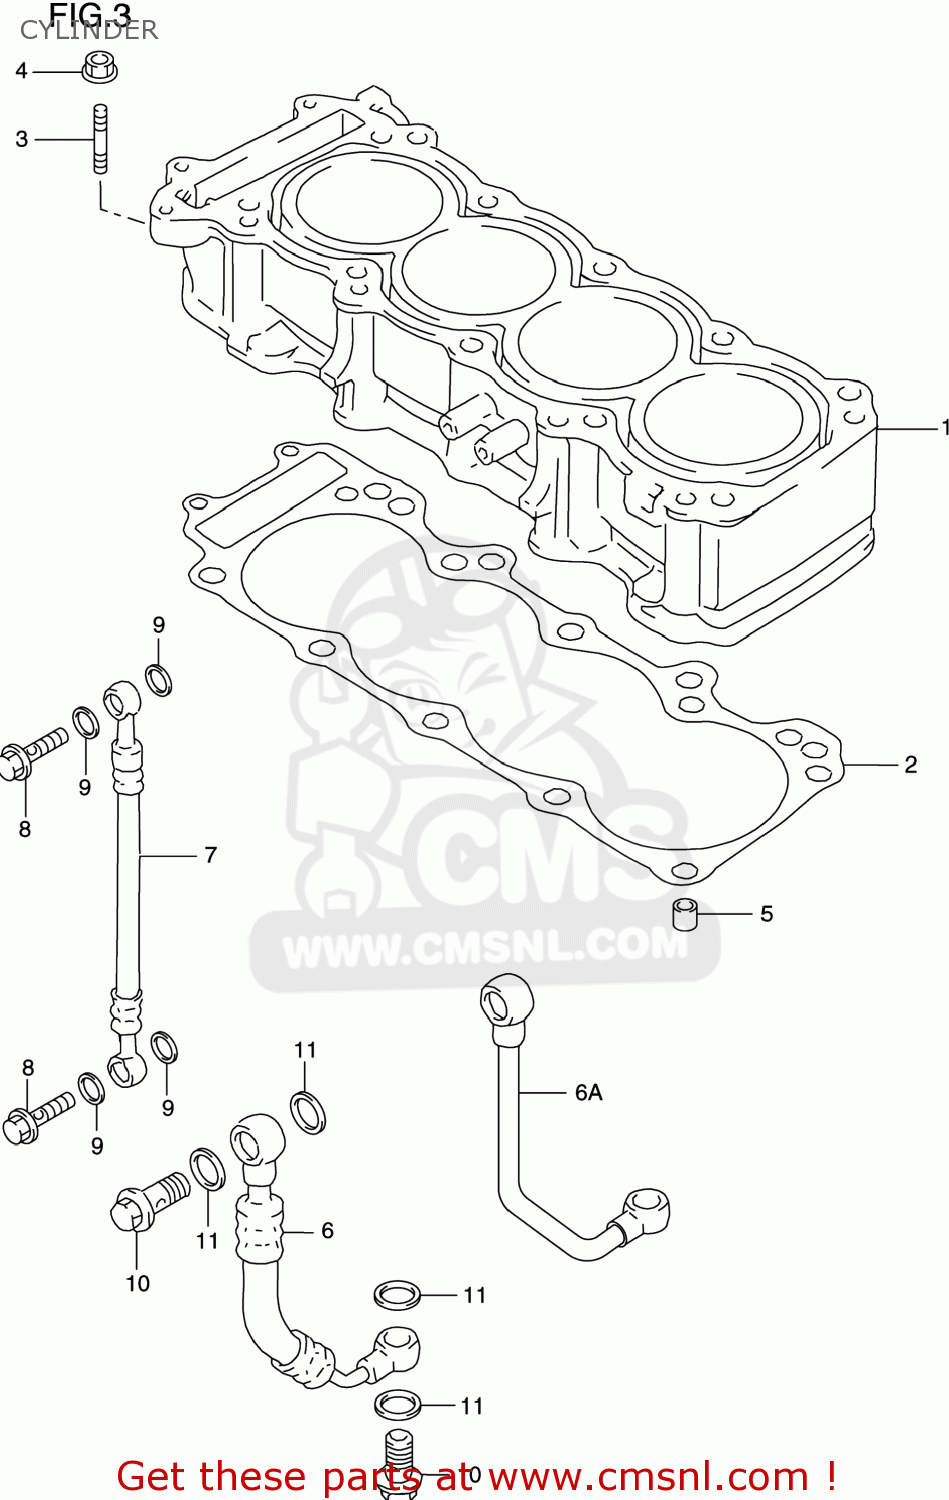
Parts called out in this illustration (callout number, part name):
1	CYLINDER
2	GASKET,CYLINDER(T:0.25)
3	STUD,M6X1X32
4	NUT
5	PIN
6	HOSE,OIL GALLERY
6A	PIPE COMP,CRANKCASE OIL
7	HOSE,CYLINDER HEAD OIL
8	BOLT UNION
9	GASKET(10.1X16X1) (NAS)
10	BOLT UNION
11	GASKET(14X20X1.5) (NAS)
